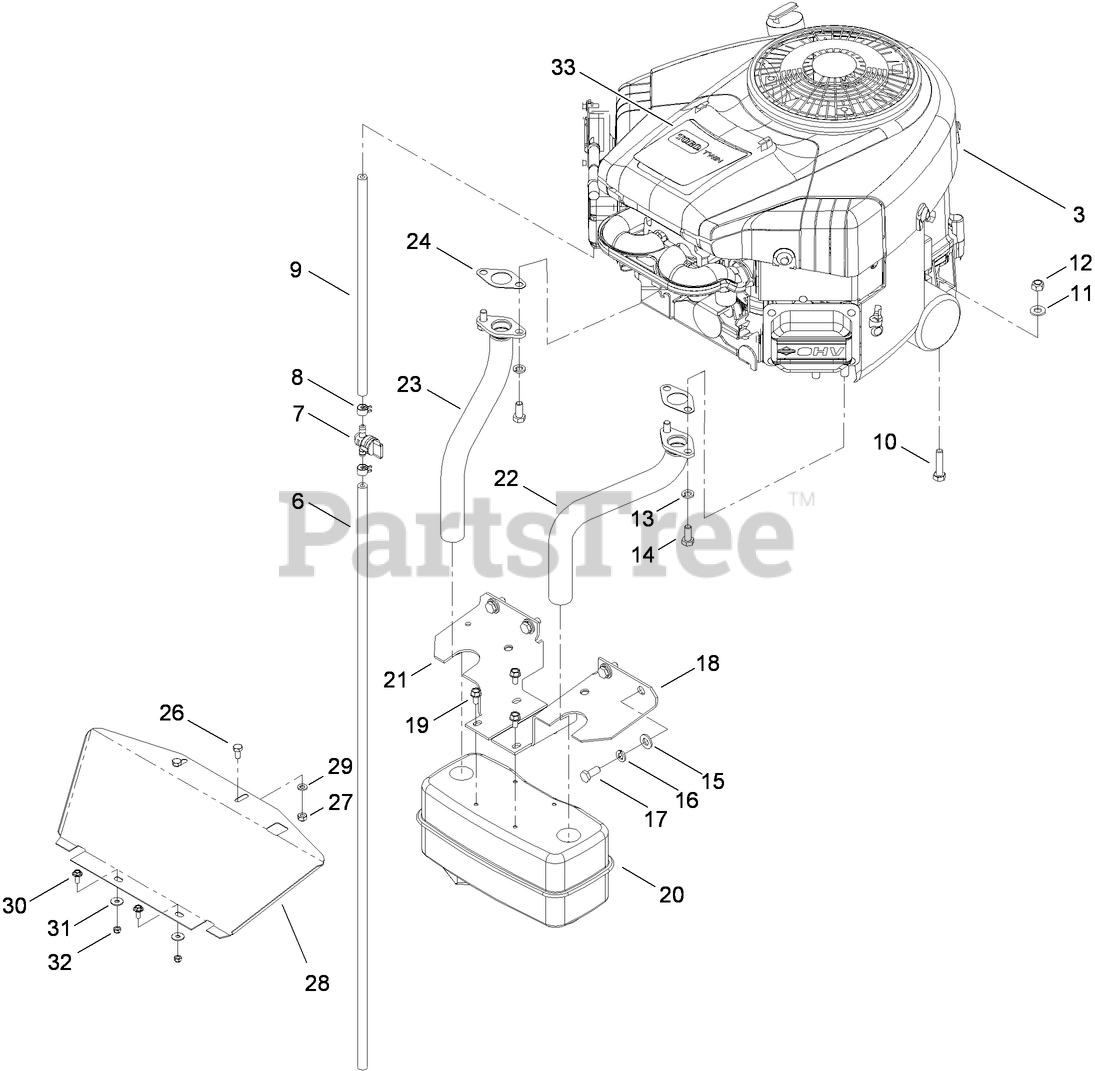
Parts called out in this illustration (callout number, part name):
6	LINE-FUEL
7	VALVE-TANK, FUEL
8	CLAMP-LINE, FUEL
10	SCREW-HH
11	WASHER-PLAIN
12	NUT-LOCK, NI
13	WASHER-SPRING
14	SCREW-HH
15	WASHER-PLAIN
16	WASHER-SPRING
17	SCREW-HH
18	GUARD-MUFFLER, LH
20	MUFFLER
21	GUARD-MUFFLER, RH
22	TUBE-EXHAUST, LH
23	TUBE-EXHAUST, RH
24	GASKET-EXHAUST
26	SCREW-HH
27	NUT-LOCK
28	SHIELD-HEAT
29	WASHER-FLAT
31	WASHER-FLAT
32	NUT-LOCK
33	DECAL-ENGINE
